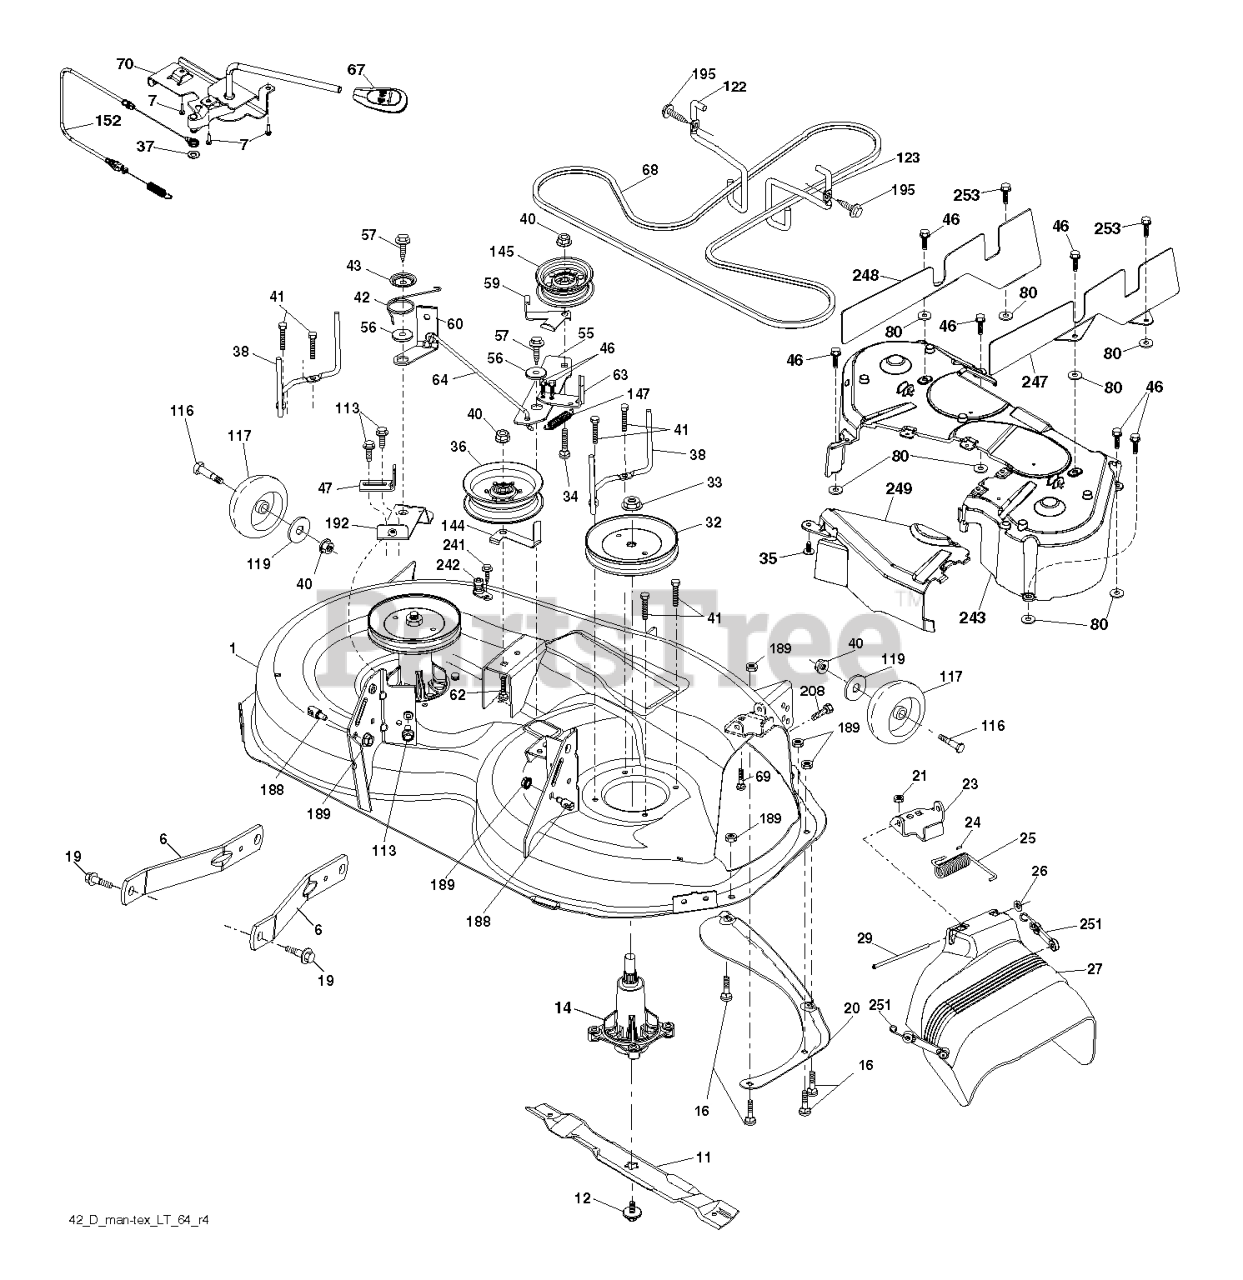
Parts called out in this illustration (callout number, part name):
1	LEVER ROD LT
2	SHAFT ASM., LIFT VGT
3	LIFT LEVER KIT
5	Washer 29/32 x 1 - 1/4 x 16 Ga.
6	BOLT
7	GRIP HANDLE
8	PLUNGER BUT KIT
9	PLUNGER BUT KIT
10	SPRING**
11	LINK LIFT
12	SPRING RETAINER
13	ARM.REAR.SUSPENSION
14	BEARING PIVOT
16	LIFT SPRING
17	NUT
19	WASHER
21	BOLT
22	FRONT LINK
23	RETAINER-SPRNG RB
24	NUT.HEX.JAM.1/2-13
25	TRUNION
26	NUT.LK.W/WSH.1/2.
32	SPRING.COMP.INF.H
33	COTTER PIN
34	ROD.LIFT.ADJUSTABLE
35	KNOB INF 3/8-16
36	SCREW
38	POINTER HGT
40	SCREW.THDROL.5/16-18X3/4.TTY
41	NUT CROWNLOCK 3/8-24
43	HEIGHT INDICATOR
70	NUT
